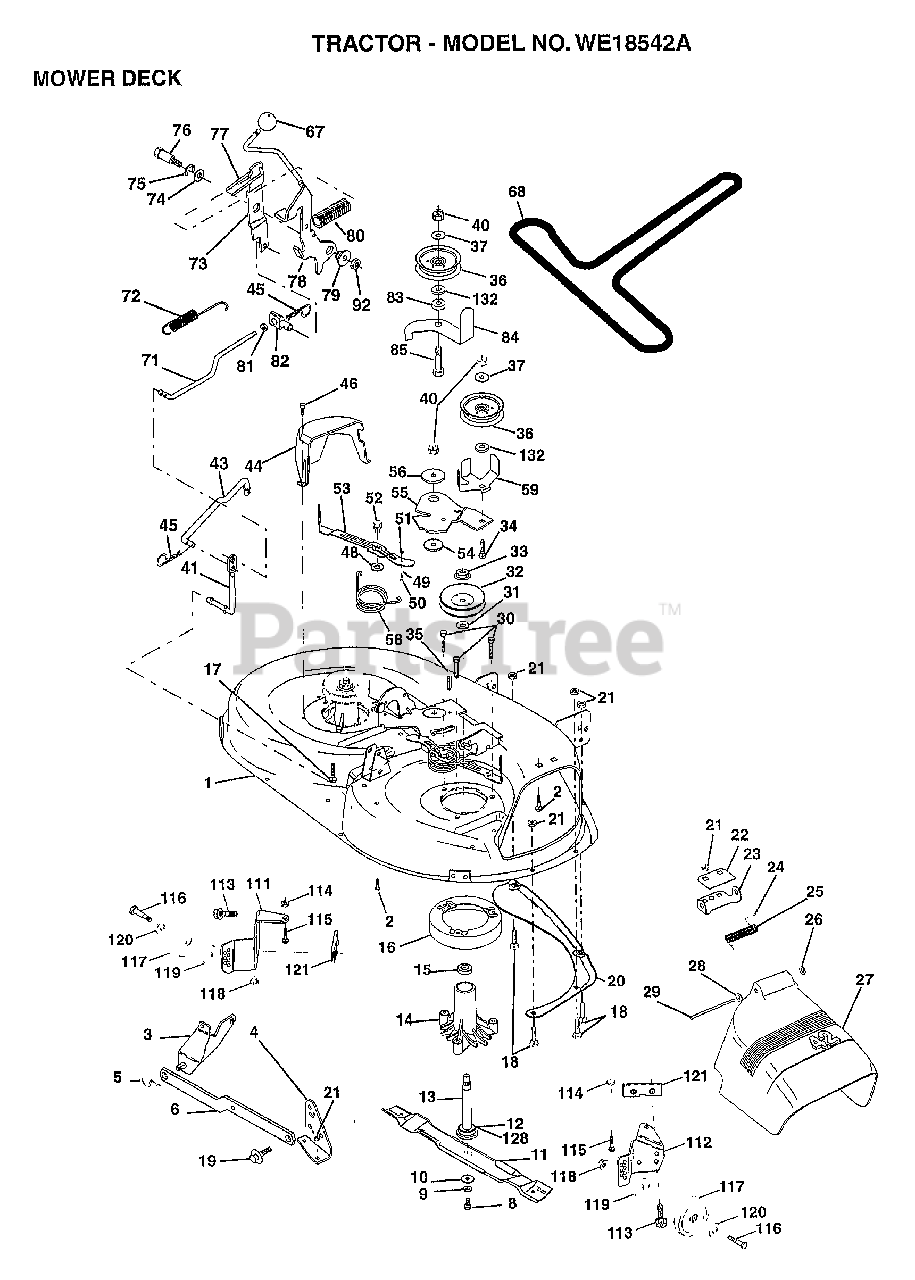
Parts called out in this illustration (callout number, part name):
1	DECK.WELD.42.
2	BOLT
3	BRKT ASM SWAY BAR
4	BRKT DECK SW BAR
8	BLADE BOLT
10	WASHER.HARD.BLADE
11	"BLADE.42"" HIPERF"
12	BEARING.BALL
14	HSG ASM MANDREL
16	STRIPPER RND MWR
17	BOLT RDHD 3/8-16
18	BOLT
19	BOLT SHD 5/16-18
22	STIFFENER BRKT
23	DEFLECTOR BRKT
24	CAP-SLEEVE LT
25	SPRING TORSION
26	NUT PUSH M
27	DEFLECTOR.SHIELD
28	WASHER
29	HINGE ROD
31	WASHER
32	PULLEY.MANDREL.42
34	BOLT
35	XMAS TREE FASTNER
36	FLAT IDLER PULLEY
37	WASHER
41	PIVOT ROD
43	ROD CLUTCH W/NIBS
44	GUARD MAND LH BLK
45	RETAINER M
46	SCREW.1/4-20X5/8
48	HARD SMALL WASHER
49	ROLLER ASM-CAM
50	SHOULDER BOLT
51	LOCKNUT
52	BOLT.SHLD.5/16-18
54	HARDENED WASHER
55	ARM-IDLER
56	SPACER RETAINER
58	SPRING TORSN BRAK
59	GUARD IDLER TUV
68	BELT.V.T-PATH
71	ROD CLUTCH 38/42
72	RETURN SPRING
73	CLUTCH ARM SECOND
74	WASHER
75	RING
76	SHOULDER BOLT
77	SPRING KEEPER
78	LEVER ASM-CLUTCH
79	BUSHING
80	SPRING.CLUTCH.MWR
81	NUT
82	TRUNION ADJ
83	WASHER
84	"KEEPER-BELT,FIXED"
85	BOLT RDHD 3/8-16
92	NUT
111	BRACKET.GWHL.LH.
112	BRACKET.GWHL.RH.
115	SCREW
116	BOLT M
117	WHEEL.GAGE.BLK.PL
118	LOCKNUT
119	WASHER
121	BRACKET.EXTRD.GWL
128	WASHER.FELT.
132	WASHER GT
